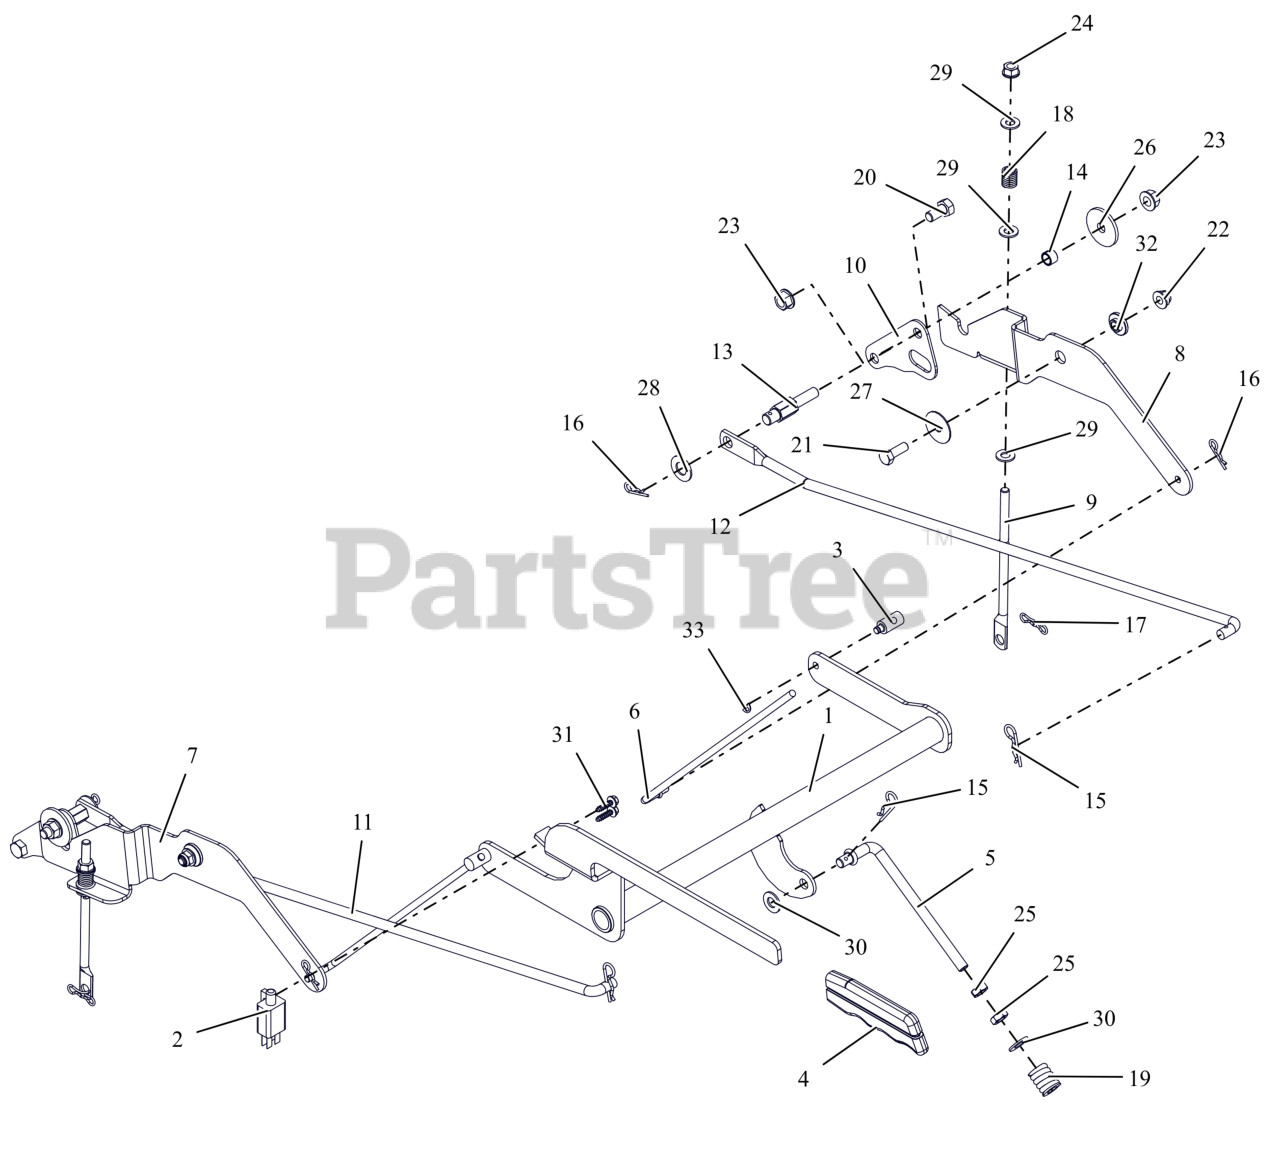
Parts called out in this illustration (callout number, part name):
1	WLDMT, BRAKE LEVER
2	SWITCH- DOUBLE POLE N.O./N.O.
3	TRUNION, 1/4-20
4	GRIP, PARKING BRAKE (YELLOW)
5	LINK, OVER CENTER, PARKING BRK
6	LINK, BRAKE ARM
7	INTERLOCK, RH BRAKE LINK
8	INTERLOCK, LH BRAKE LINK
9	LINK, BRAKE COG
10	PLATE, TRANSAXLE ADAPTOR
11	LINKAGE, STEERING - RH
12	LINKAGE, STEERING - LH
13	POST, STEERING LINK MOUNTING
14	SPCR, SLV .385X.500X.350
15	PIN, HAIR #203 .09X1.50 ZCC
16	PIN, HAIR #213 .08X1.19 ZCC
17	PIN, BOWTIE #72 ZCC
18	SPRING, COMPRESSION
19	SG-COMP .187X.56X1.62
20	BLT,HEX .38-16X.75 G5 ZCC
21	BLT, HEX .31-18X.875 G5 ZCC
22	NUT,LK-NYL-FLG .31-18 G5ZC120
23	NUT-LK-CTR-FLG .375-16 GF ZCC
24	NUT,LK-CTR-FLG .31-18 GF ZCC
25	NUT-JAM .375-16 G2 ZCC
26	WSHR, FLT .380X1.50X.125 ZCC
27	WSHR, FLT .347X1.254X.048 ZCC
28	WSHR, FLT .505X1.00X.062 ZCC
29	WSHR,FLT .344X.688X.065 ZCC
30	WSHR,FLT .406X.812X.065 ZCC
31	SCR, PLASTITE #12X.75 ZCC
32	BSHG, FLG .325X.499X.26X.88
33	RG-RTNG-EXT .250X.025
